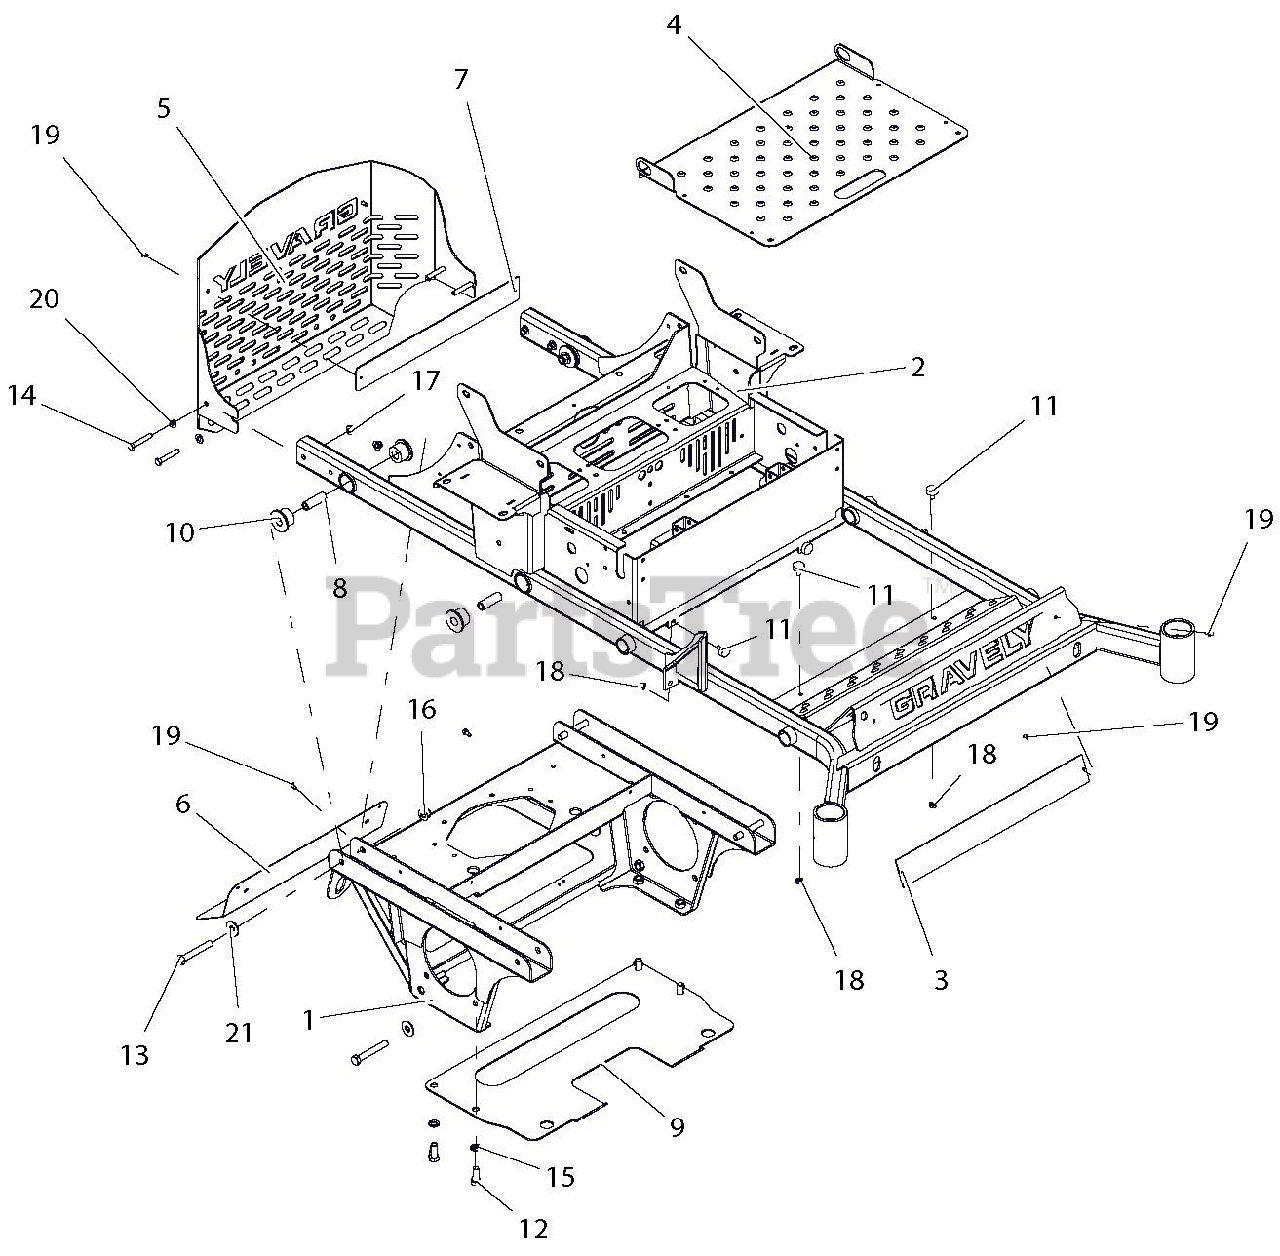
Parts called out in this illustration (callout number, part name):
1	WLDT, 200 PT AXLE/ENGINE FRAME
2	WLDMT, 52"-66" PT200 MAIN FRAME W/SAFETY DECALS
3	PLATE, BUMPER NAME BACKER
4	PANEL, INSPECTION
5	PRO-TURN 200 REAR BUMPER W/ SAFETY DECALS
6	SHIELD, MUFFLER HEAT
7	PLATE, BUMPER PRO-TURN 200
8	SPCR, .50 X .75 X 2.23 YZ
9	PLATE-TRANSMISSION SKID
10	BSHG, FLANGE .750 X 1.510 X 1.130 X 2.000
11	BUMPER, RUBBER
12	BLT-HEX .50-13X1.25 GR5 YWZC
13	BLT-HEX .50-13X3.50 GR5 YWZC
14	BLT-HEX .38-16X2.25 GR5 YWZC
15	WSHR-LK .50X.125 REG YWZC
16	NUT-LK-NYL-FLG .50-13 YWZC
17	NUT-LK-NYL-FLG .38-16 YWZC
18	@NUT-SPNLK-FLG .312-18 YWZC
19	SCR-TAP .25-20X.50 HWH TR YWZ
20	WSHR-FL-STL.406X.812X.065 YWZ
21	WSHR-FL-STL.563X1.38X.109YWZC
